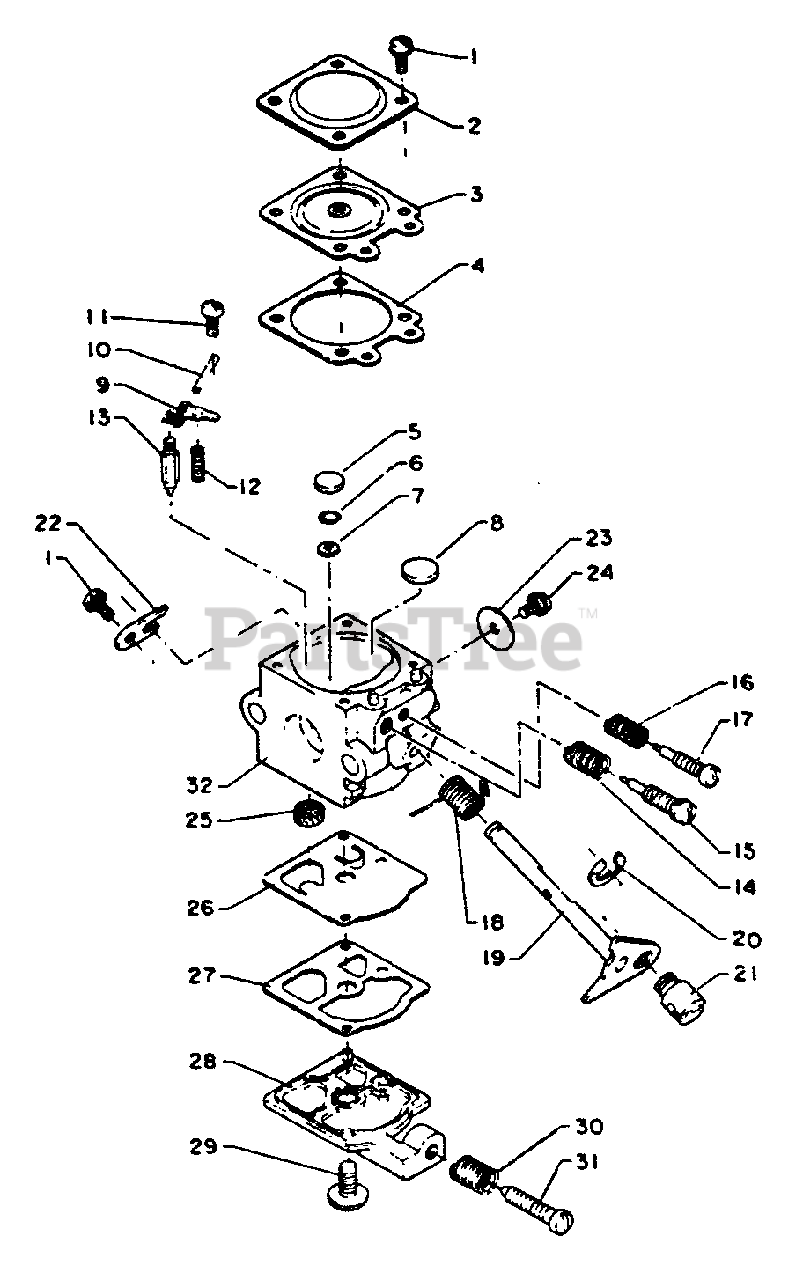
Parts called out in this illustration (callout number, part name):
1	SCREW
2	COVER, METERING
3	DIAPHRAGM, METERING
4	GASKET, METERING
5	PLUG, WELCH
6	RING, RETAINING
7	STRAINER
8	PLUG, WELCH
9	LEVER, METERING
10	PIN, METERING LEVER
11	SCREW, METERING LEVER PIN
12	SPRING, METERING LEVER
13	VALVE, INLET NEEDLE
14	SPRING, HIGH SPEED NEEDLE
15	NEEDLE - HIGH SPEED
16	SPRING
17	NEEDLE - LOW SPEED
18	SPRING, THROTTLE RETURN
19	SHAFT, THROTTLE
20	RING, RETAINING
22	CLIP, THROTTLE SHAFT
23	VALVE, THROTTLE
25	STRAINER
26	DIAPHRAGM, PUMP
27	GASKET, PURGE
28	COVER, PUMP
29	SCREW, PUMP COVER
30	SPRING, IDLE ADJUST
31	SCREW, IDLE ADJUST
32	BODY, CARBURETOR
